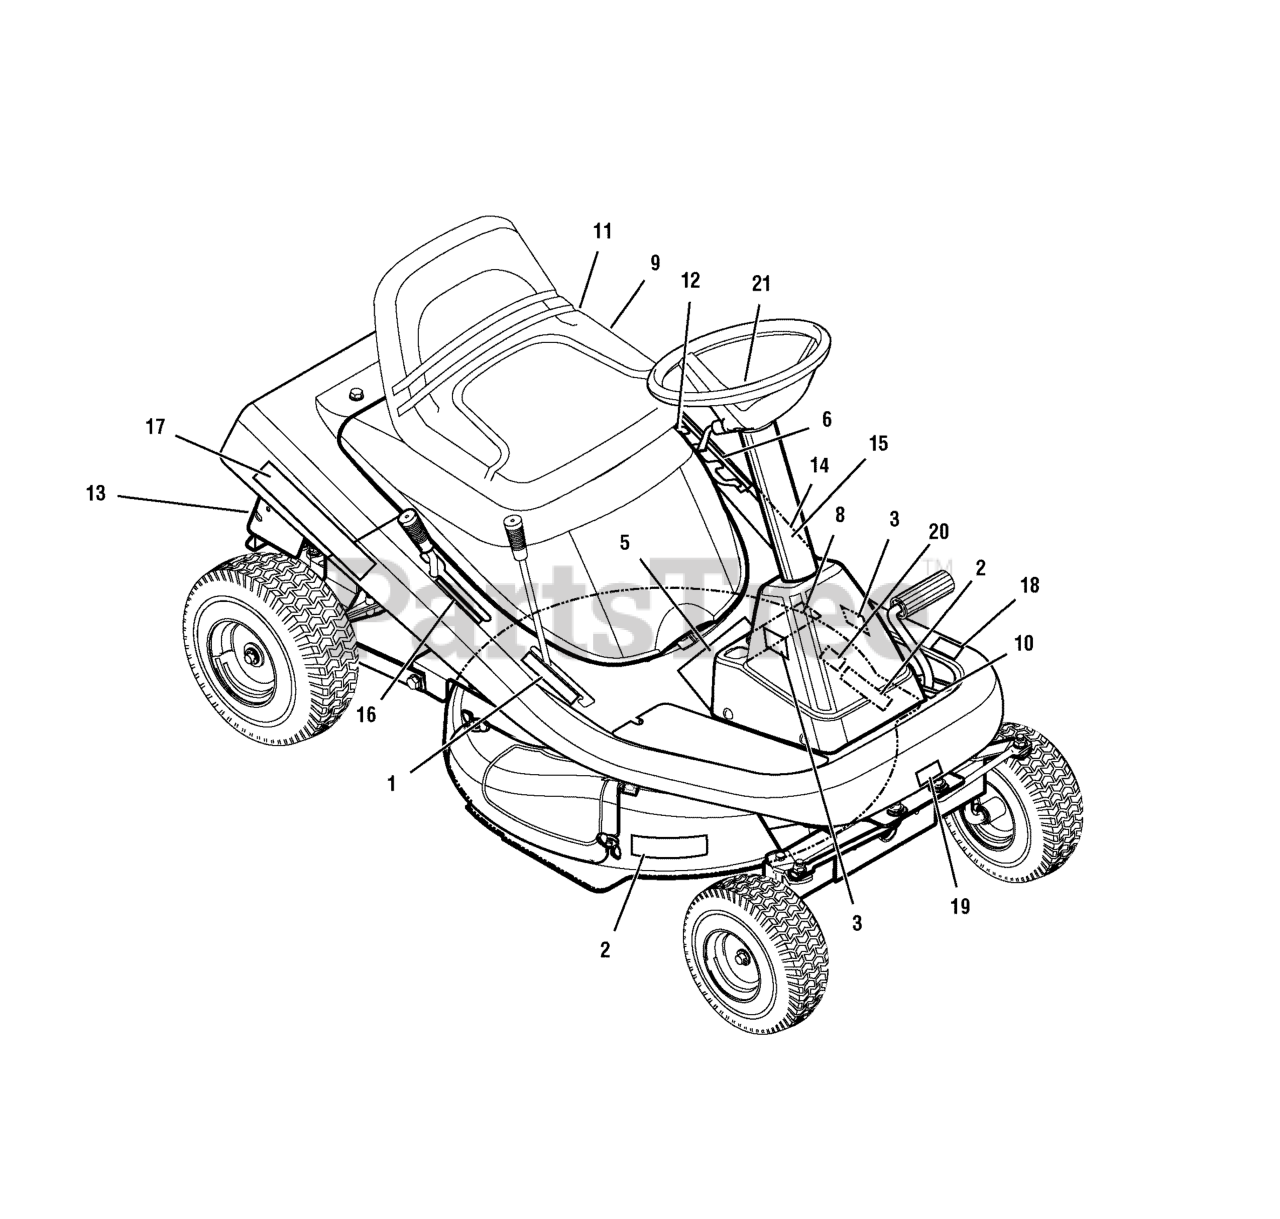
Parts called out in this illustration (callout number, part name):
1	DECAL, Engagement
2	DECAL, Cut Finger Signal
3	DECAL, 105/76 Model Series RM50
5	DECAL, Warning, Export
6	DECAL, Height Adjust, 6 Positions
8	DECAL, Park Brake Symbol
9	DECAL, Throttle Control
10	DECAL, Clutch/Brake XPT
11	DECAL, Gas Gauge
12	DECAL, Heat Shield Warning
13	DECAL, Warning Load Limit, Export
14	DECAL, Warning Pinch Point
15	DECAL, Deck Level
16	DECAL, Gear Select, 5 Speed
17	DECAL, Murray Logo
18	DECAL, 100db, Export
19	DECAL, Briggs 10.5
20	DECAL, DECK WIDTH 76cm
21	DECAL, STEERING WHEEL
